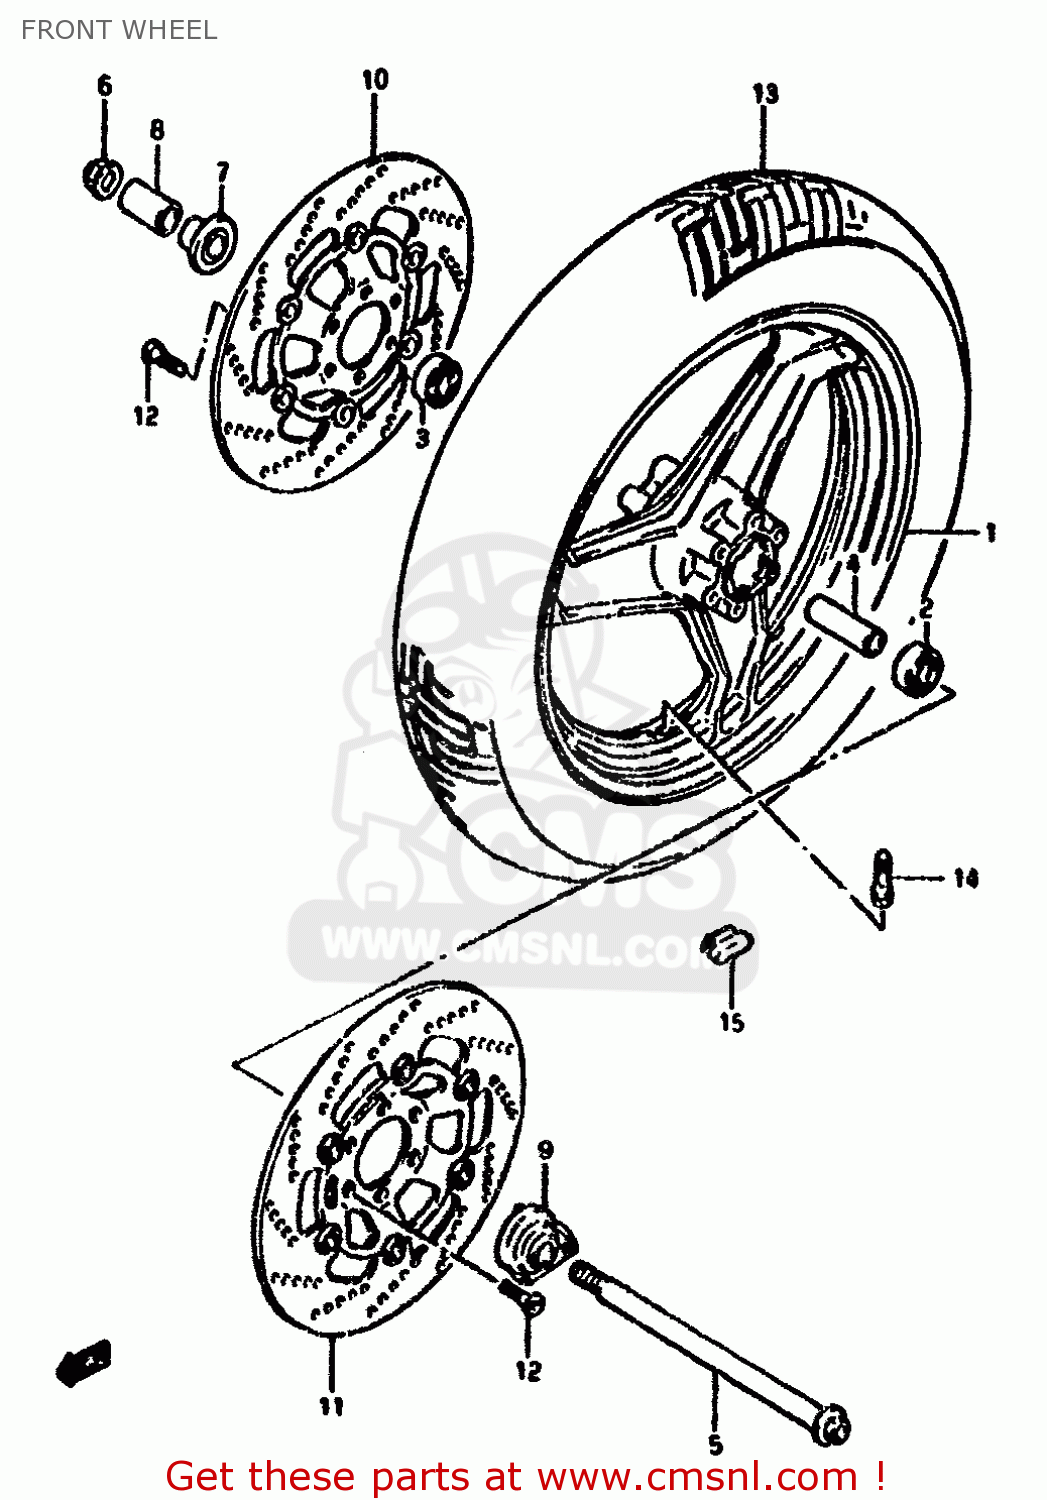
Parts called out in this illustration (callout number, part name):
1	WHEEL, FRONT (MT2.75X16) BLAC
2	BEARING(17X42X13)
3	BEARING
4	SPACER (17.3X24X78)
5	AXLE,FR
6	NUT
7	SPACER COMP,FRONT HUB,RIGHT
8	SPACER,FRONT AXLE,RIGHT
9	BOX ASSEMBLY,SPEEDOMETER GEAR
10	DISC,BRAKE
11	DISC,BRAKE
12	BOLT 8X33
13	TIRE,FRONT
14	VALVE,TIRE
15	BALANCER,WHEEL
